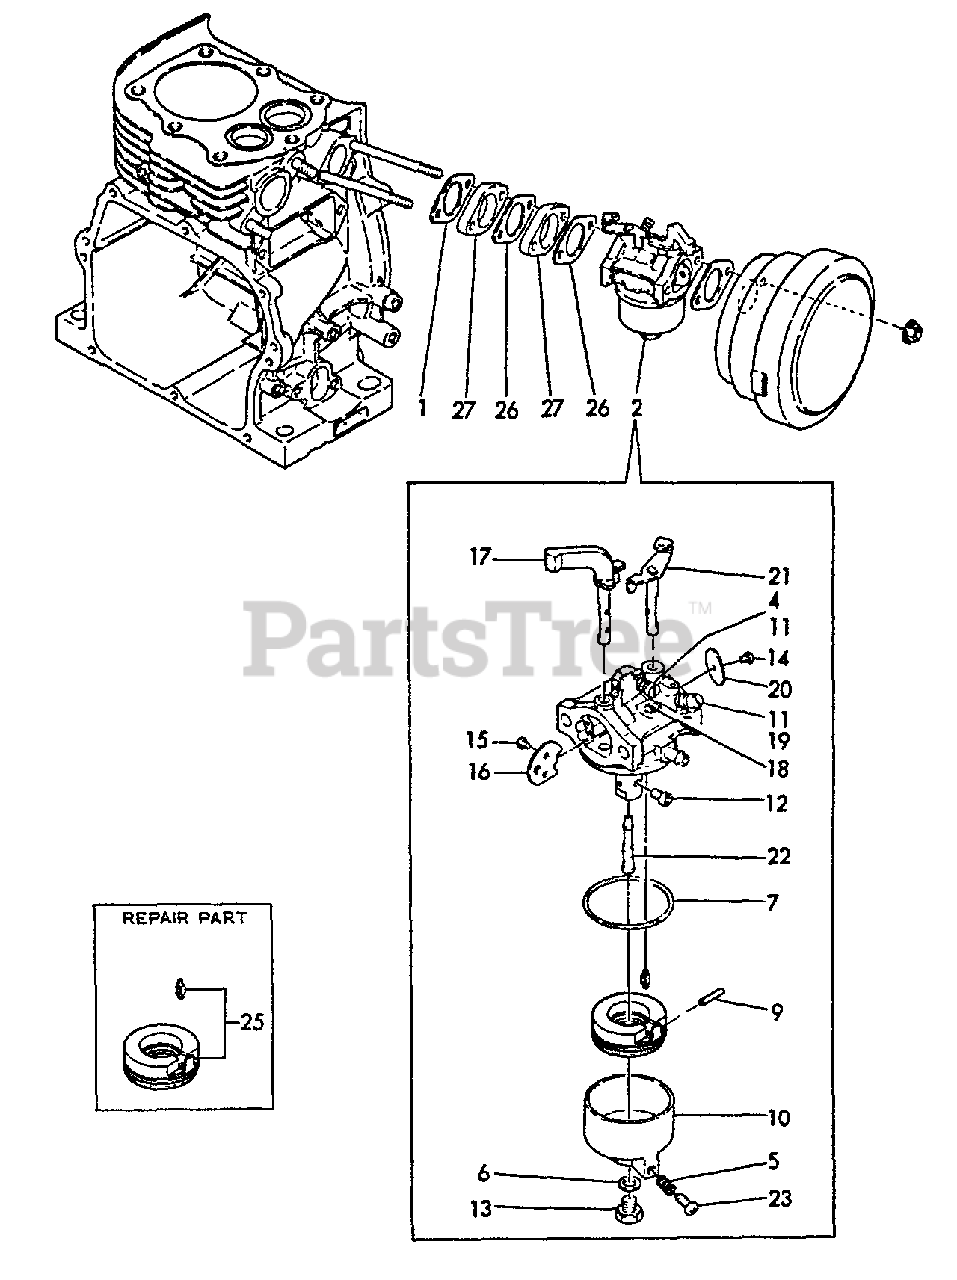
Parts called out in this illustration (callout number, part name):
1	GASKET, EXHAUST
2	CARBURETOR
4	SCREW, THROTTLE
6	WASHER
7	GASKET
9	PIN
10	BODY, FLOAT CHAMBER
12	JET, MAIN
13	BOLT
14	SCREW
15	SCREW -- TAPPING
16	VALVE, CHOKE
17	SHAFT, CHOKE
18	JET, PILOT
19	SCREW
20	VALVE, THROTTLE
21	SHAFT, THROTTLE
22	NOZZLE, MAIN
23	SCREW
25	NEEDLE ASSY - RUBBER
26	GASKET, INTAKE
27	INSULATOR, INTAKE
